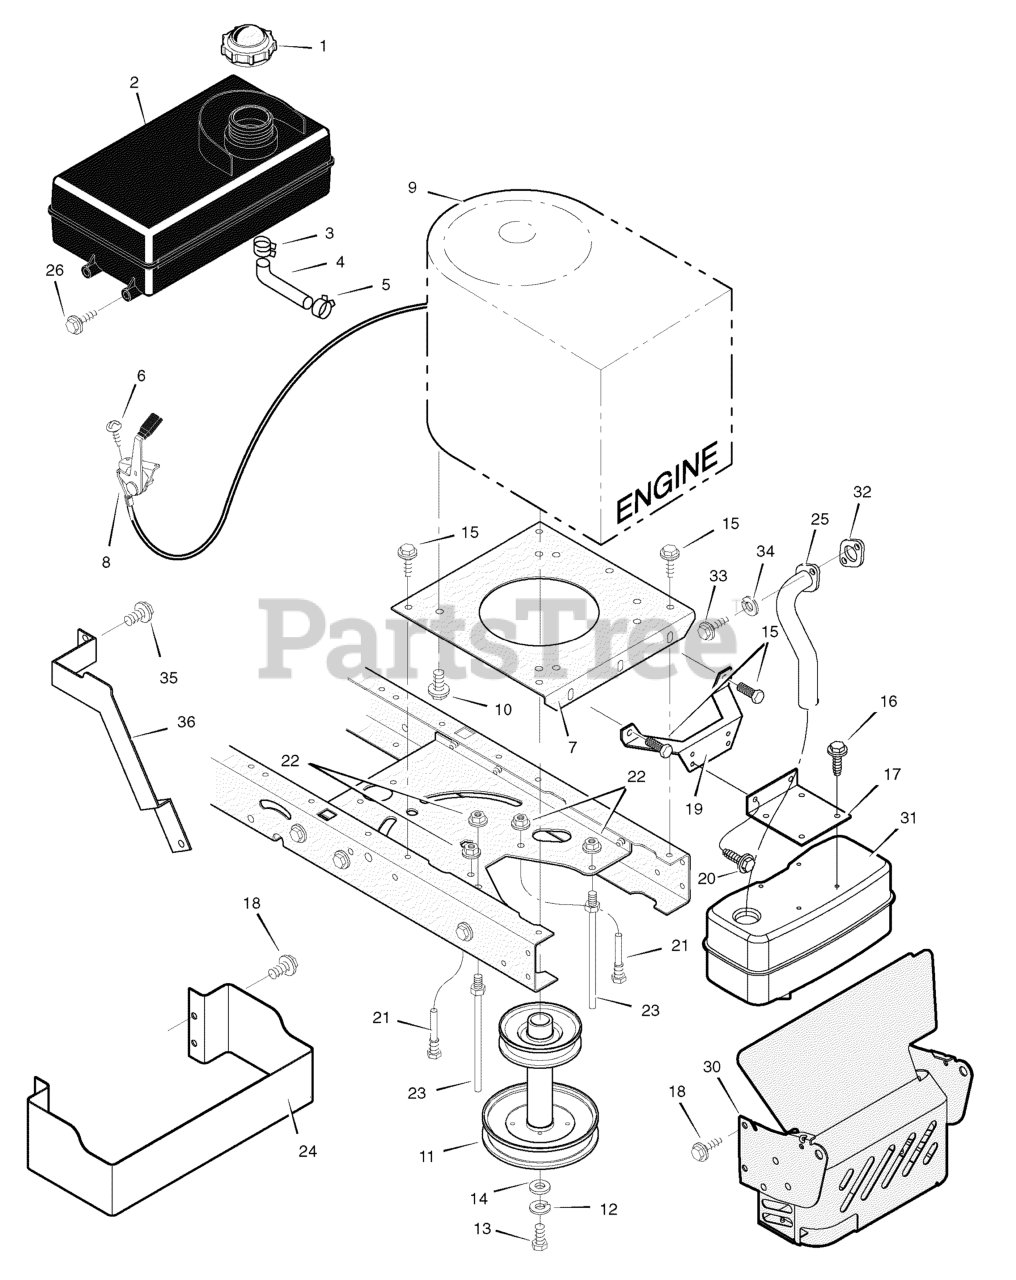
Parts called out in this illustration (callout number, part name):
1	Fuel Cap
2	TANK, Fuel 1.4 Gal.
3	Hose Clamp
4	Fuel Line (Must cut to length)
5	Hose Clamp
7	Plate, Engine
8	Throttle Control
9	Engine, Briggs & Stratton *
10	Bolt, Engine Mount
11	STACK PULLEY ASSEMBLY
12	Lockwasher
13	Bolt, Hex
17	Bracket, Muffler
19	Bracket, Muffler Mount
21	Guide, Belt
22	Nut, Flange
23	Guide, Belt
24	GUARD, Heat Shield
25	Exhaust Tube, Single
30	Shield, Heat
31	Muffler
32	GASKET, Exhaust
34	Washer
35	Bolt, Washer Hex Head
36	Guard, Exhaust Pipe
